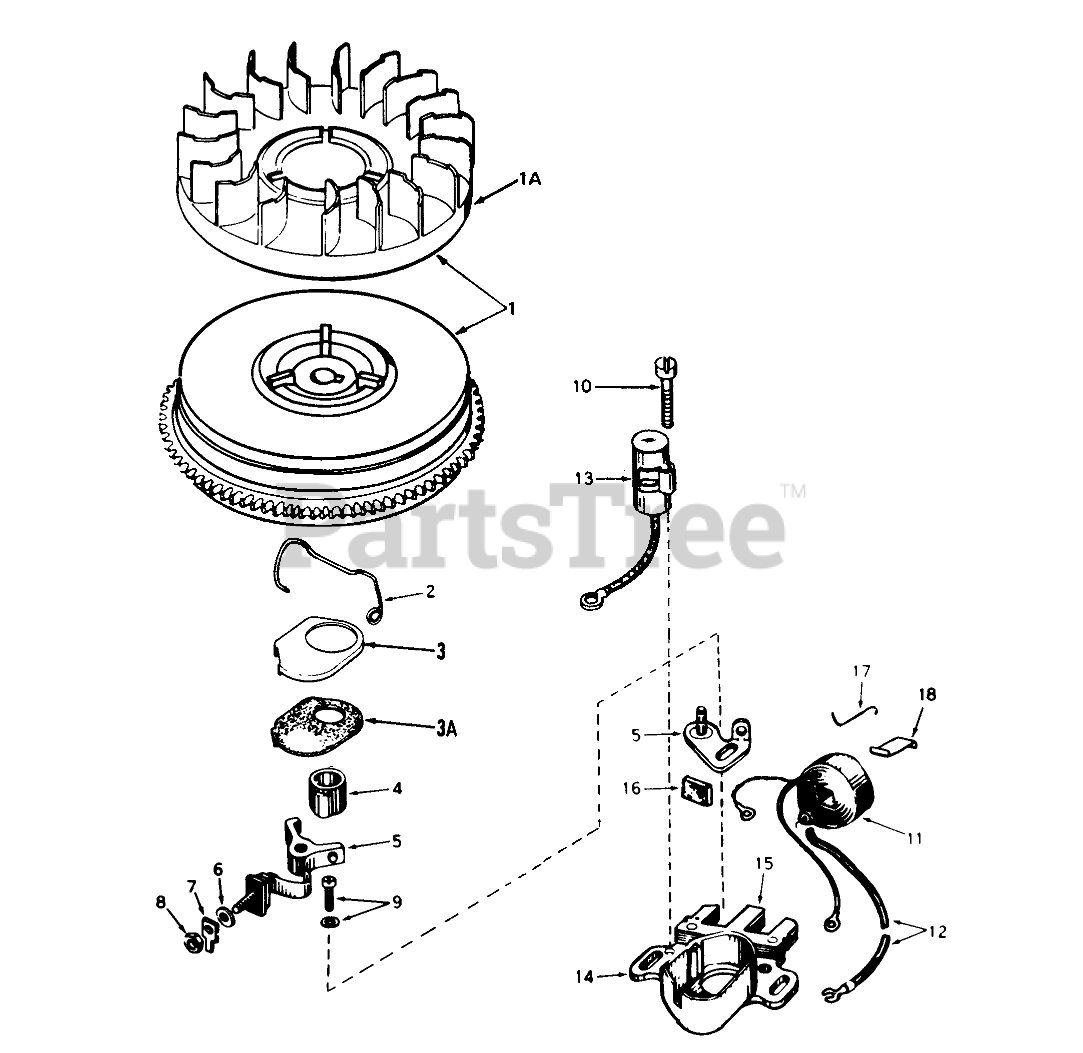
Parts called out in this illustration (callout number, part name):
1	Flywheel (Incl. Nos. 1A, 3 & 3A)
2	Spring Breaker Box
3	Cover-Dust
3A	Gasket, Dust Cover
4	Cam-Breaker
5	Breaker Assy.
7	Terminal, Ground
9	Breaker Screw
10	Condenser Screw
11	Coil Assy. (Incl. No. 12)
12	Wire, Lead
13	Condenser
14	Core & Plate
15	Stator Assy. (Incl. Nos. 2, 3, 3A, 5 thru 14 & 16 thru 18)
16	Felt,Cam Wiper
17	Clip, Coil
18	Spring Coil Wedge
